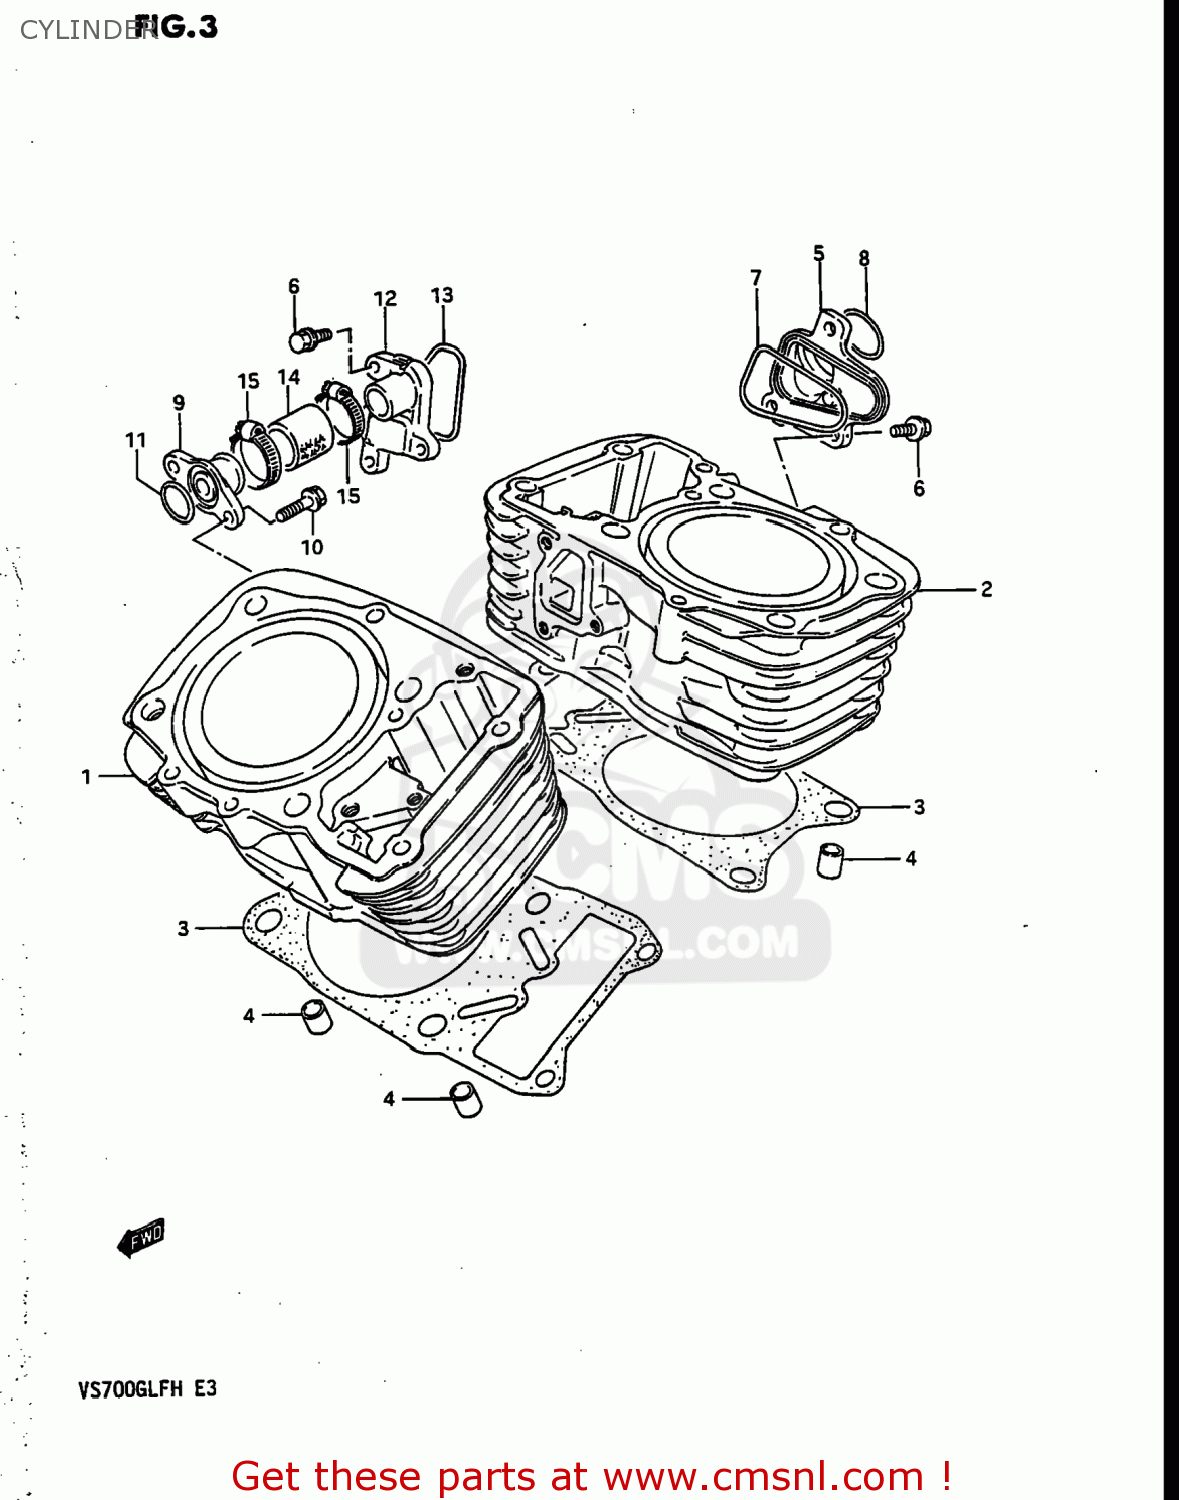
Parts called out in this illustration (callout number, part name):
1	CYLINDER
2	CYLINDER,REAR
3	GASKET,CYLINDER (MCA)
4	PIN
5	CHAMBER,WATER,INLET
6	BOLT (6X20)
7	O RING,INLET WATER CHAMBER
8	O RING(D:2.3,ID:24.4)
9	UNION,WATER INLET
10	M6 BOUTJES
11	O RING(D:2.4,ID:15.8)
12	CHAMBER,WATER,OUTLET
13	O RING,OUTLET WATER CHAMBER
14	HOSE,RADIATOR
15	CLAMP
